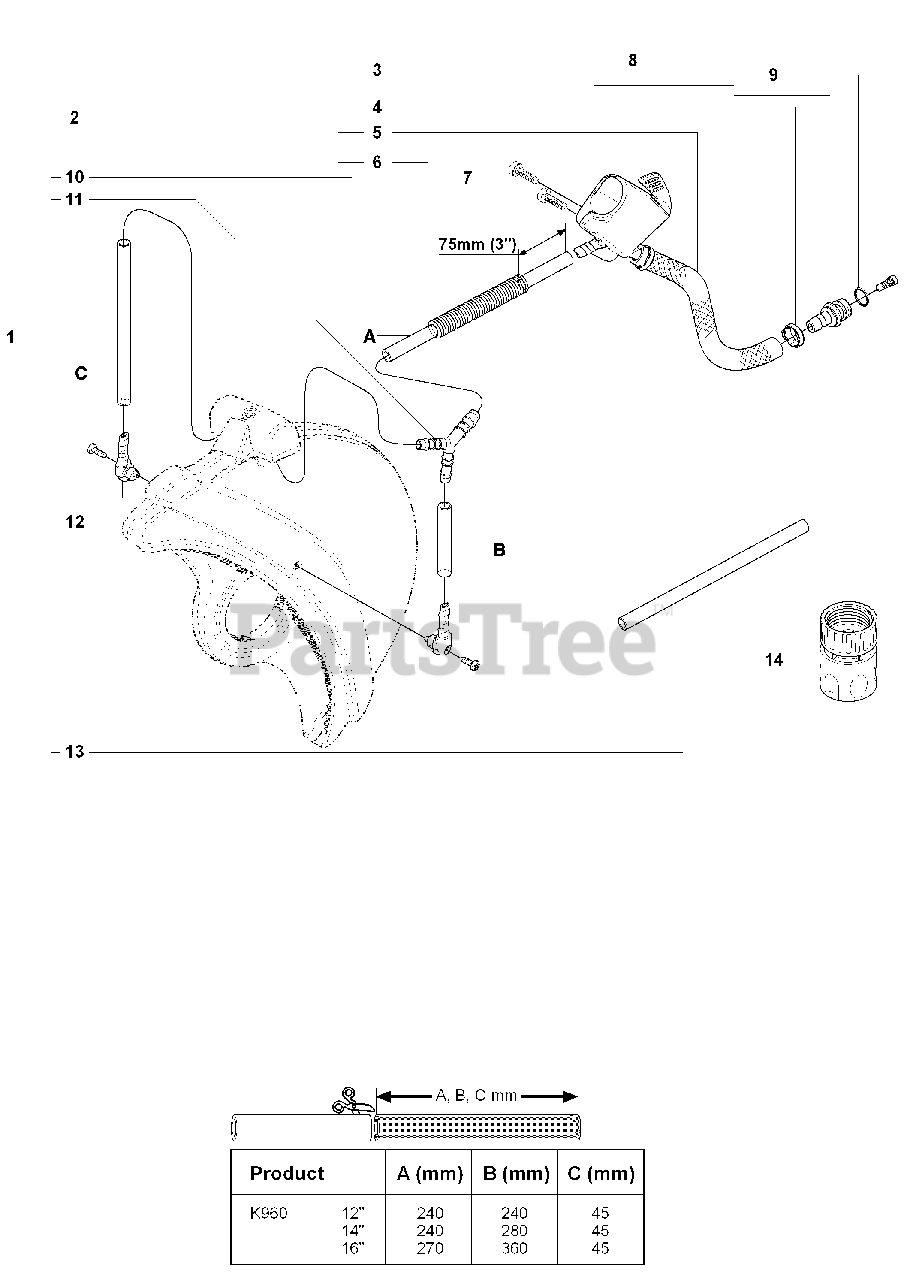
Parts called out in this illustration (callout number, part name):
1	WATER HOSE KIT
2	HOSE
3	NIPPLE
4	HOSE CLAMP
5	HOSE
6	VALVE ASSY
8	FILTER
9	O-RING
10	PROTECTIVE SPRING
13	HOSE
14	COUPLER
